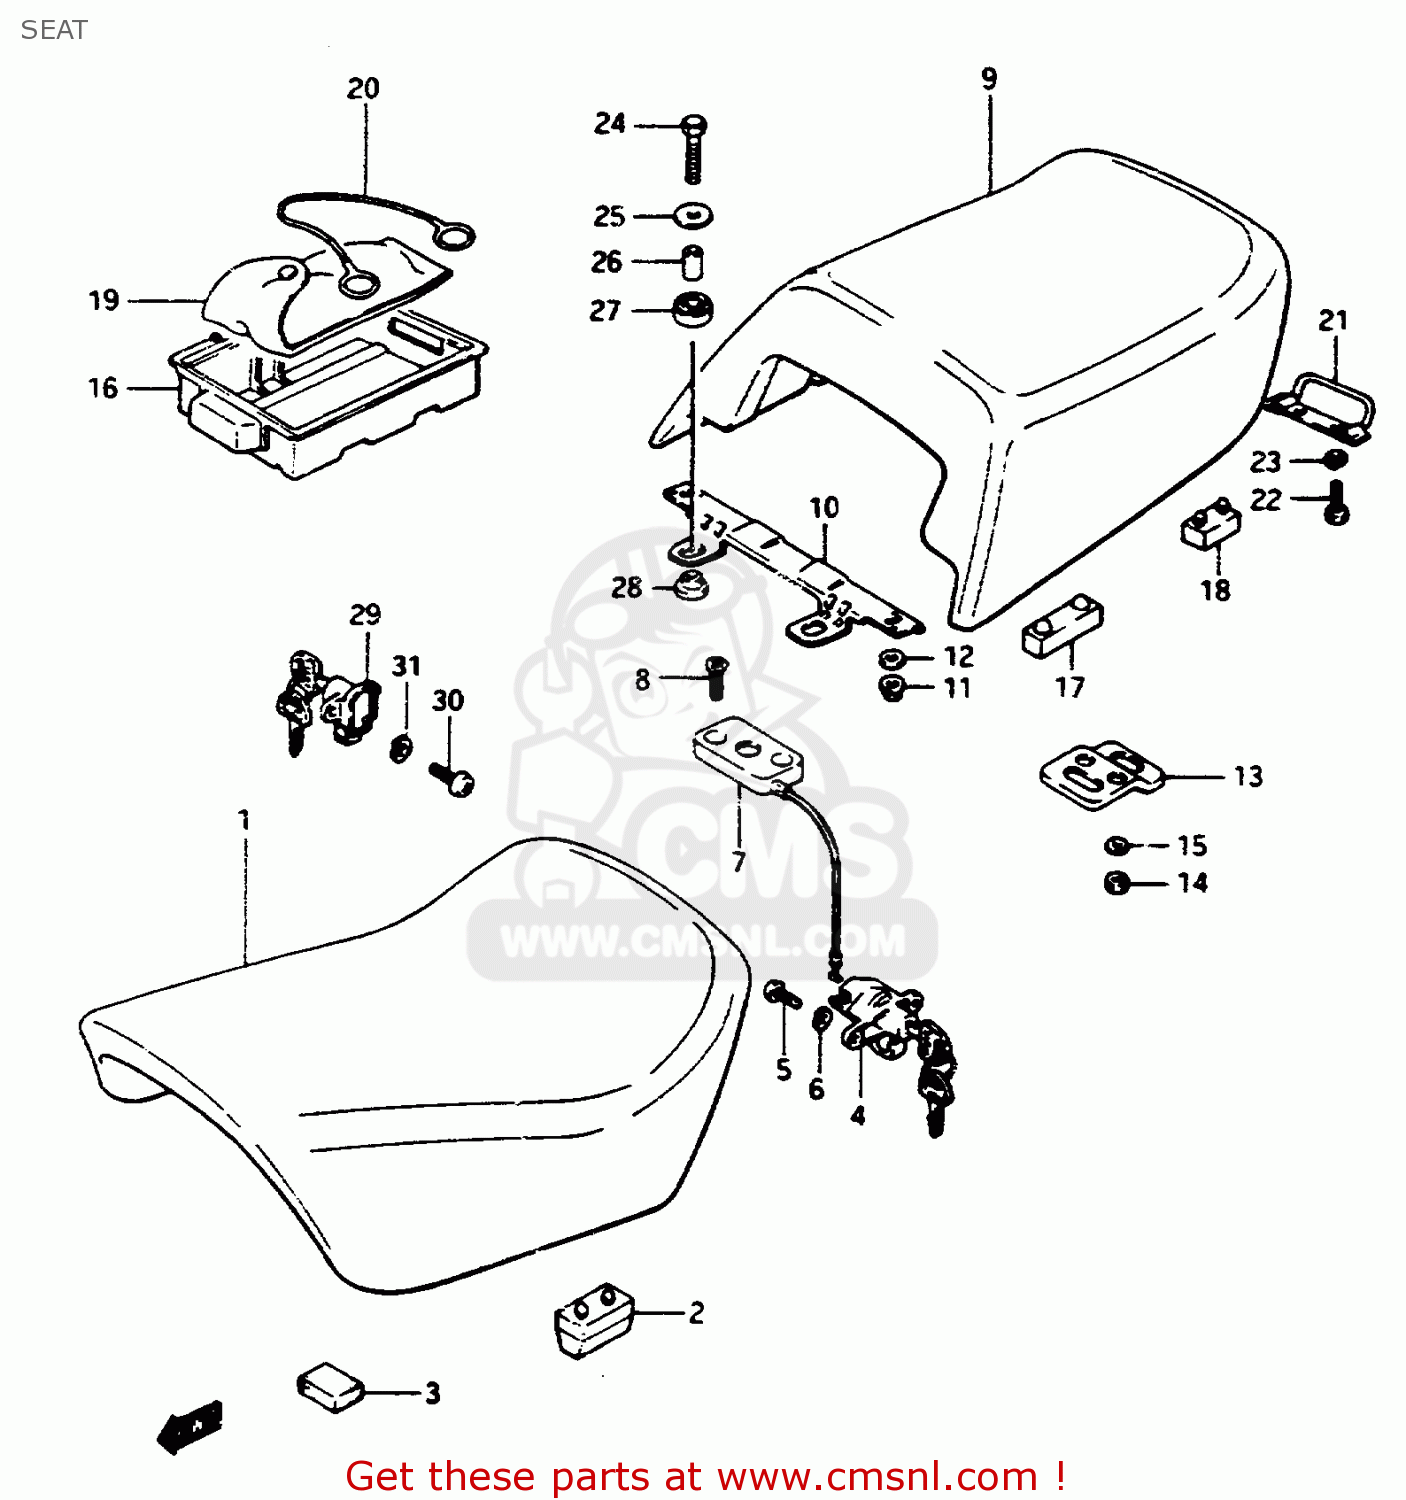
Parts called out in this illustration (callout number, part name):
1	SEAT SET (BLUE)
2	CUSHION,SEAT
3	CUSHION,TOOL(40X30X15)
4	LOCK ASSEMBLY,SEAT & HELMET
5	SCREW
6	WASHER,LOCK
7	BRACKET,SEAT SUPPORT
8	SCREW
9	SEAT ASSEMBLY,PILLION
10	PLATE,PILLION SEAT,FRONT
11	NUT
12	WASHER,LOCK
13	PLATE, SEAT HOOK REAR
14	NUT
15	WASHER,LOCK
16	TOOL BOX
17	CUSHION,SEAT
18	CUSHION(40X23X12.7)
19	TOOL SET
20	BAND,TOOL BOX
21	PLATE,SEAT HOOK,REAR
22	BOLT
23	WASHER,LOCK
24	SCREW(6X30)
25	WASHER (6.5X24X1.6)
26	SPACER
27	CUSHION
28	CUSHION
29	LOCK ASSEMBLY,HELMET
30	SCREW
31	WASHER,LOCK
